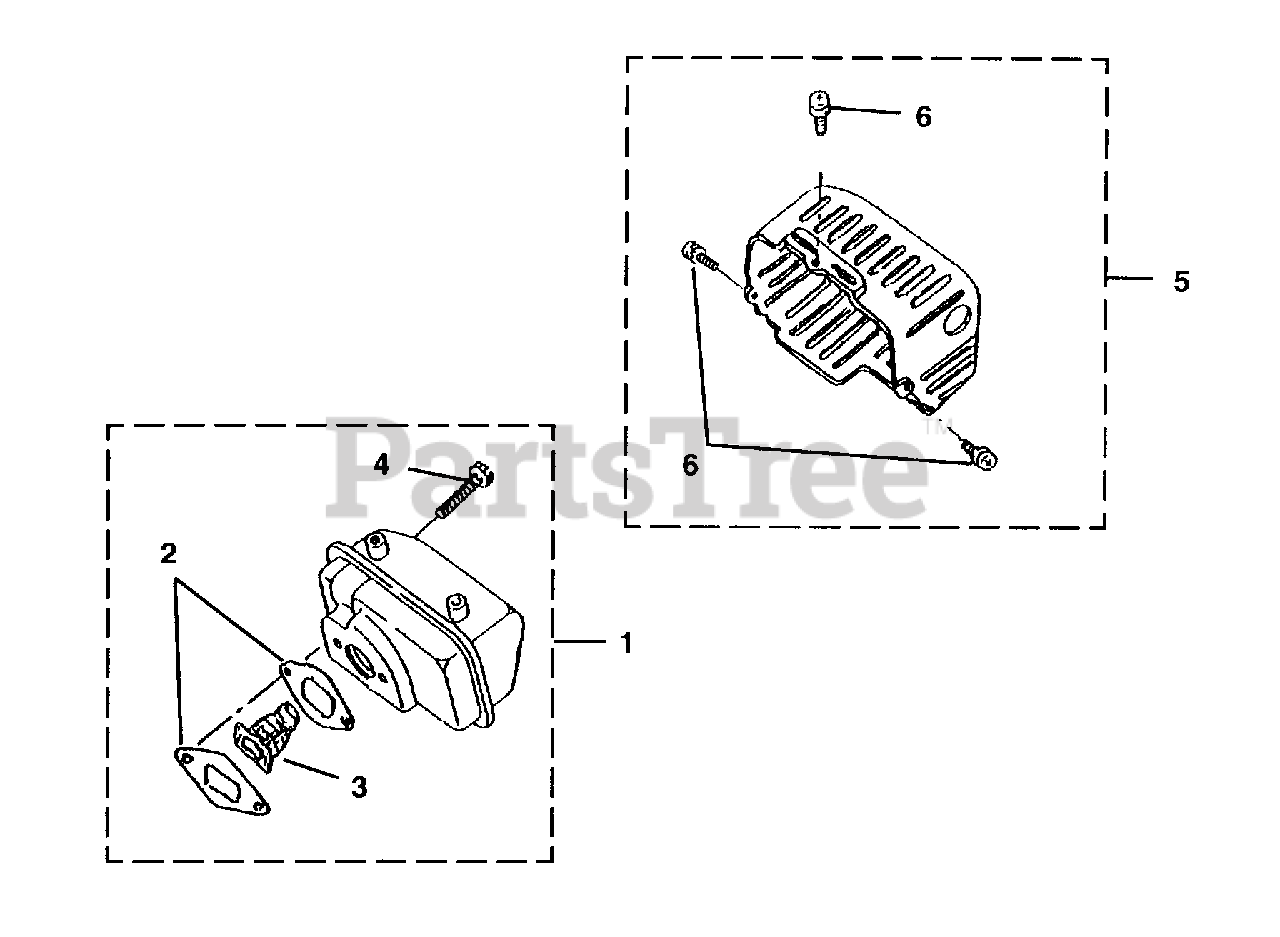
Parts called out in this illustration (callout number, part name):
1	MUFFLER ASSEMBLY
2	GASKET Muffler
3	SPARK ARRESTER
4	SCREW-Socket Hd (M6 X 60 SW)
5	MUFFLER COVER
6	SCREW (MS x 14 W SW)
